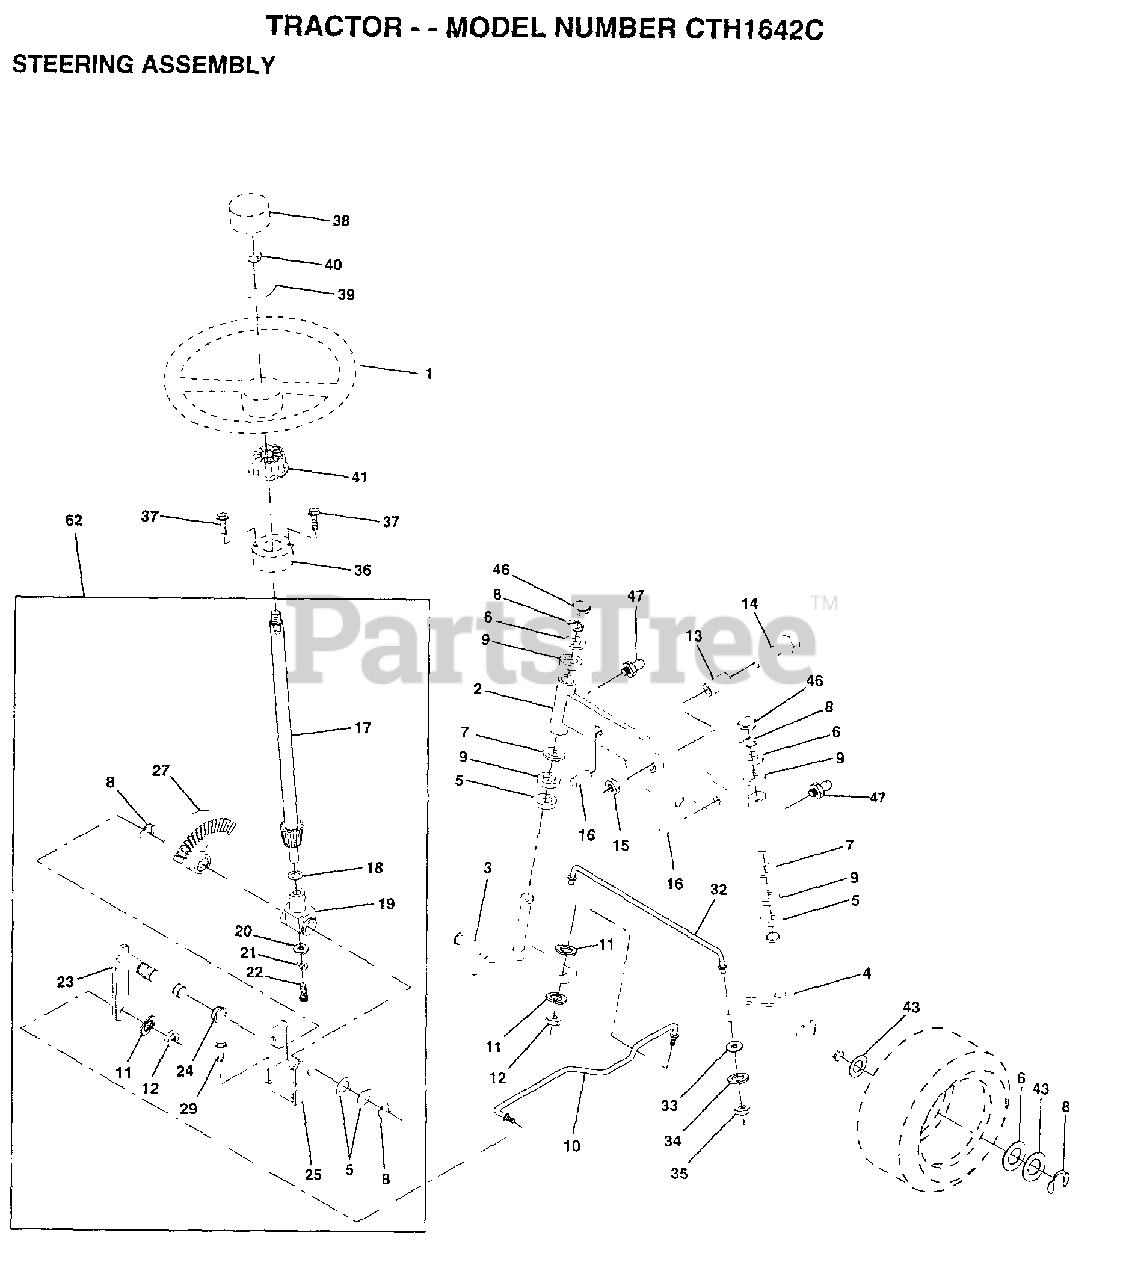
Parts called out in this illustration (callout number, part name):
1	WHEEL STR AYP BLK
2	AXLE ASM FRONT
3	SPINDLE LH
4	SPINDLE RH
5	WASHER .T
6	WASHER
7	WASHER
8	RING
9	COL. SRTG. BEAR.
11	LOCKWASHER
13	BEARING
14	BOLT HEX 5/8-11
15	"NUT-LOC,FLANGE LT"
16	AXLE PIN
17	STEERING SHAFT
18	THRUST WASHER
19	SUPPORT.SHAFT
21	LOCKWASHER
22	SCREW.SCKTHD.CAP
24	NYLINER T
25	"BRKT,STEERING"
27	GEAR SECTOR
29	SCREW
32	ROD.TIE.19.75
33	WASHER M
34	LOCKWASHER
35	NUT.LOCK.5/16-24
36	BUSHING.STRG.3/4
37	"SCREW-TT,10-32 FL"
38	CAP STEER AYP
39	WASHER
41	ADAPTER LT
43	WASHER
46	CAP
47	ZERK M
